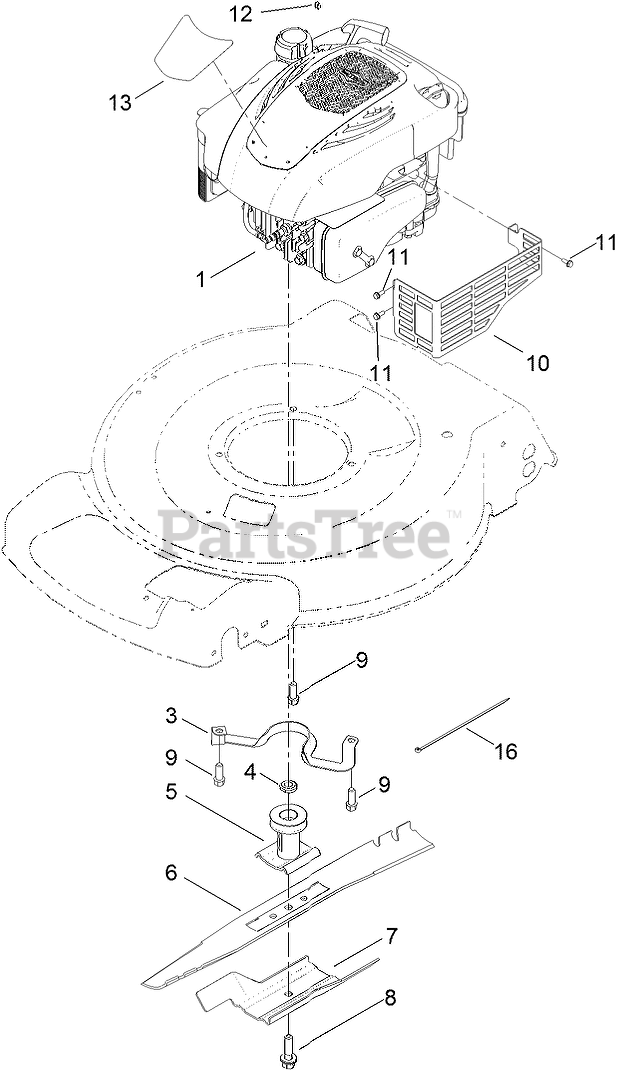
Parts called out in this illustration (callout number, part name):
3	Guide-Belt
4	Spacer-Driver
5	DRIVER-BLADE
6	BLADE
7	Accelerator-Blade
8	BOLT-BLADE
9	SCREW-TAPTITE
10	SHIELD-MUFFLER
11	SCREW-TAPTITE
12	STOP-ROPE
13	DECAL-SHROUD
16	TIE-CABLE, MOTOR
